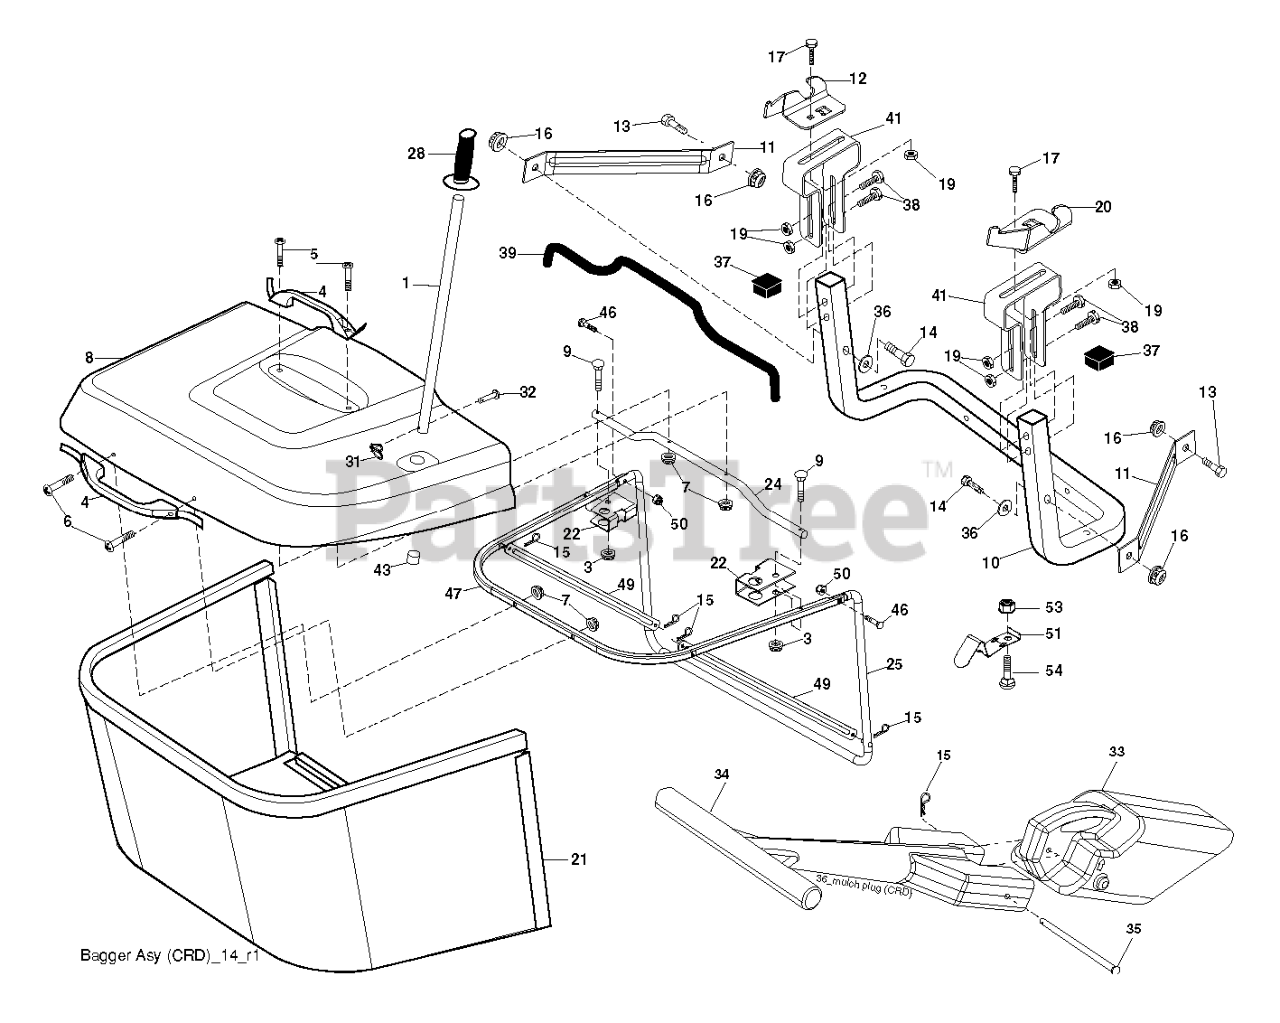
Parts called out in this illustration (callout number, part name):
1	TUBE HANDLE
3	NUT T
4	HANDLE.BAGGER.W/LVRS.BLK.CRD
5	SCREW.PAN.HEAD
6	REPL BY 532 75 00-29
8	COVER.PNT.BGR.CRD.WSLOTS.MS668
9	Bolt Carriage 1/4-20 x 2.25d x Gr.5
10	TUBE
11	BRACKET.SUPPORT.UPPER.BAG.CRD
12	BRKT PIVOT
14	BOLT-HEX EAK
15	RETAINER-SPRNG RB
16	NUT LOCK FLG 3/8-16 UNC
17	RP BOLT 5/16-18 X3/4 ZN/YEL GR
19	NUT LOCK HEX FLANGE 5/16-18
20	BRKT.PIVOT.RH.CRD
21	BAGGER.ASM.CRD.2007
22	BRKT.SIDE.BAG.CRD
24	TUBE.PIVOT.BAG.CRD.BLACK
25	PIPE
28	GRIP.HANDLE.BLACK
31	RETAINER CLIP
32	RIVET,DRILLED
33	PLUG.MULCHER.92 CRD
34	HANDLE.MULCHER.92.CRD (2 2)
36	WASHER
37	Plug Support Bagger CRD
38	BOLT.5/16-18X2.5
39	SEAL.BAGGER.CRD
41	BRKT.VERT.ADJ.BAGGER.CRD
43	PLUG, TUBING END
46	BOLT.CARRIAGE.5/16-18
47	PIPE
49	ROD
50	NUT.71038.31-18.HEX.NYLOCK
51	LATCH
53	NUT
54	BOLT
